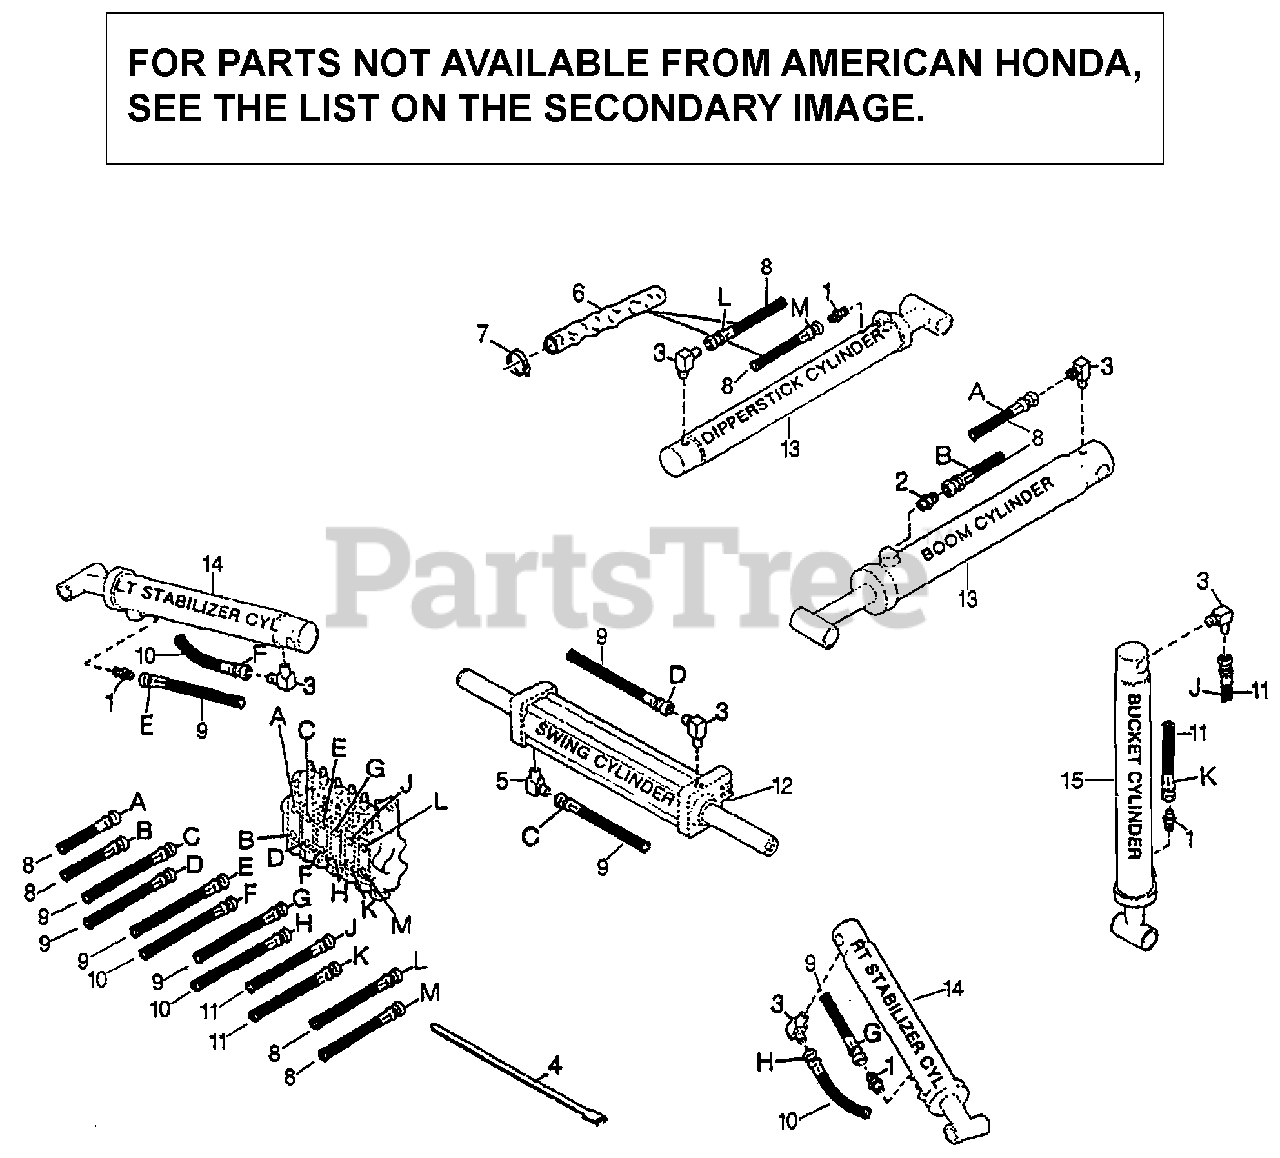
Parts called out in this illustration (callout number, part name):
4	HOSE, HYDRAULIC TIE (7")
7	SLEEVE, HOSE (13")
8	HOSE ASSY., FEMALE HIGH PRESSURE (9/16-18X99")
9	HOSE ASSY., FEMALE HIGH PRESSURE (9/16-18X49")
10	HOSE ASSY., FEMALE HIGH PRESSURE (9/16-18X50")
11	HOSE ASSY., FEMALE HIGH PRESSURE (9/16-18X124")
12	CYLINDER, SWING
13	CYLINDER, HYDRAULIC (2-1/2X16-3/4)
14	CYLINDER, STABILIZER
15	CYLINDER, HYDRAULIC (2X16-3/4)
